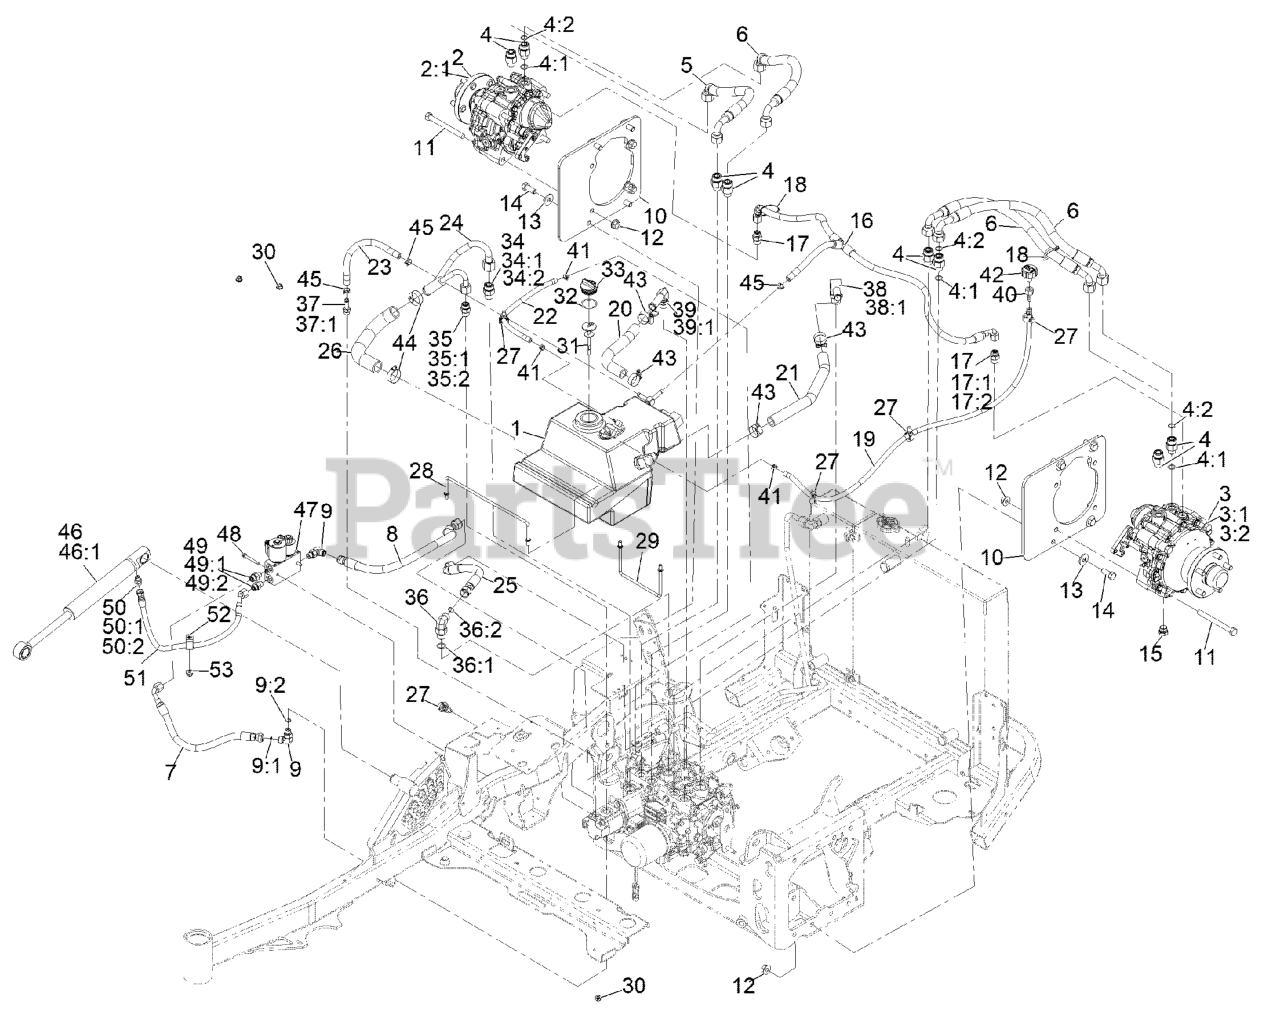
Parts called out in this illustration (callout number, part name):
1	HYD RESERVOIR ASM
2	MOTOR-HYD, RH
2:1	5 STUD WHEEL HUB KIT
3	MOTOR-HYD, LH
3:1	5 STUD WHEEL HUB KIT
3:2	SEAL KIT
4	FITTING-STRAIGHT
4:1	O-RING
5	HOSE ASM
6	HOSE ASM
7	HOSE ASM
8	HOSE ASM
9	FITTING-ELBOW, 90 DEG
9:1	O-RING
9:2	O-RING
10	PLATE-MOTOR
11	SCREW-HH
12	NUT-HHF
13	WASHER-SPRING
14	SCREW-HH
15	PLUG-MAGNETIC
16	TEE HOSE ASM
17	FITTING-STRAIGHT
17:1	O-RING
17:2	O-RING
18	TIE-CABLE
20	HOSE-RETURN
21	HOSE-RETURN
24	TUBE ASM
25	HOSE ASM
26	HOSE-SUCTION
27	CLIP-TIE
28	ROD-SUPPORT, HYD TANK
29	ROD-SUPPORT, HYD TANK
30	NUT-HF, NI
31	DIPSTICK
33	PLUG-PLASTIC
34	FITTING-STRAIGHT
34:1	O-RING
34:2	O-RING
35	FITTING-STRAIGHT
35:1	O-RING
35:2	O-RING
36	FITTING-ELBOW, 90 DEG
36:1	O-RING
36:2	O-RING
37	ADAPTER-STRAIGHT
37:1	O-RING
38	FITTING-ELBOW, 90
38:1	O-RING
39	FITTING-90
39:1	O-RING
40	FITTING-STRAIGHT
41	CLAMP-HOSE
42	BREATHER
43	CLAMP-HOSE
44	CLAMP-HOSE
45	CLAMP-HOSE
46	CYLINDER-LIFT
46:1	CYL Repair Kit
47	DECK LIFT VALVE ASM
48	SCREW-HWHTF
49	FITTING-STRAIGHT
49:1	O-RING
49:2	O-RING
50	FITTING-HYD, STRAIGHT
50:1	O-RING
50:2	O-RING
51	HOSE ASM
52	CLIP-LOOM
53	NUT-HF, NI
